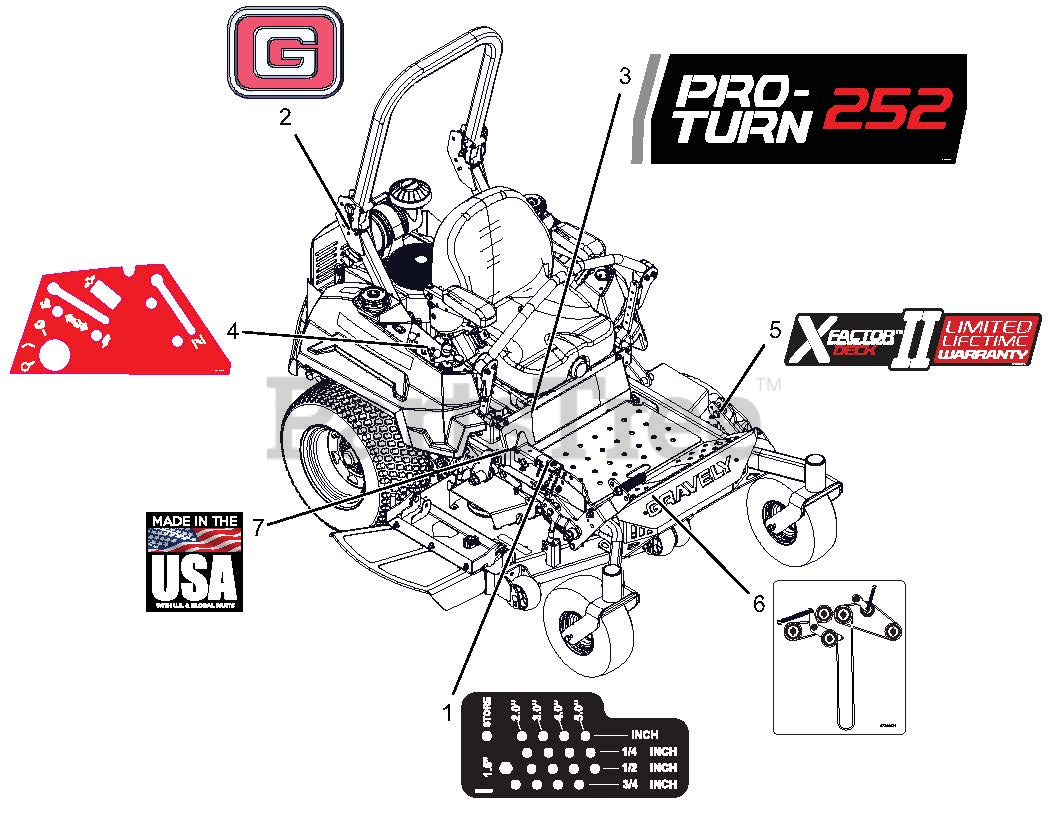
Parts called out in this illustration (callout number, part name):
1	DECAL, HEIGHT OF CUT
2	DECAL, GRAVELY BRAND
3	DECAL, PRO-TURN 252
4	DECAL, NON-EFI CONTROL PANEL
5	DECAL, X-FACTOR DECK
6	DCL,BELT ROUTE-RH V-SIDE IDLER
7	DECAL, MADE IN USA
